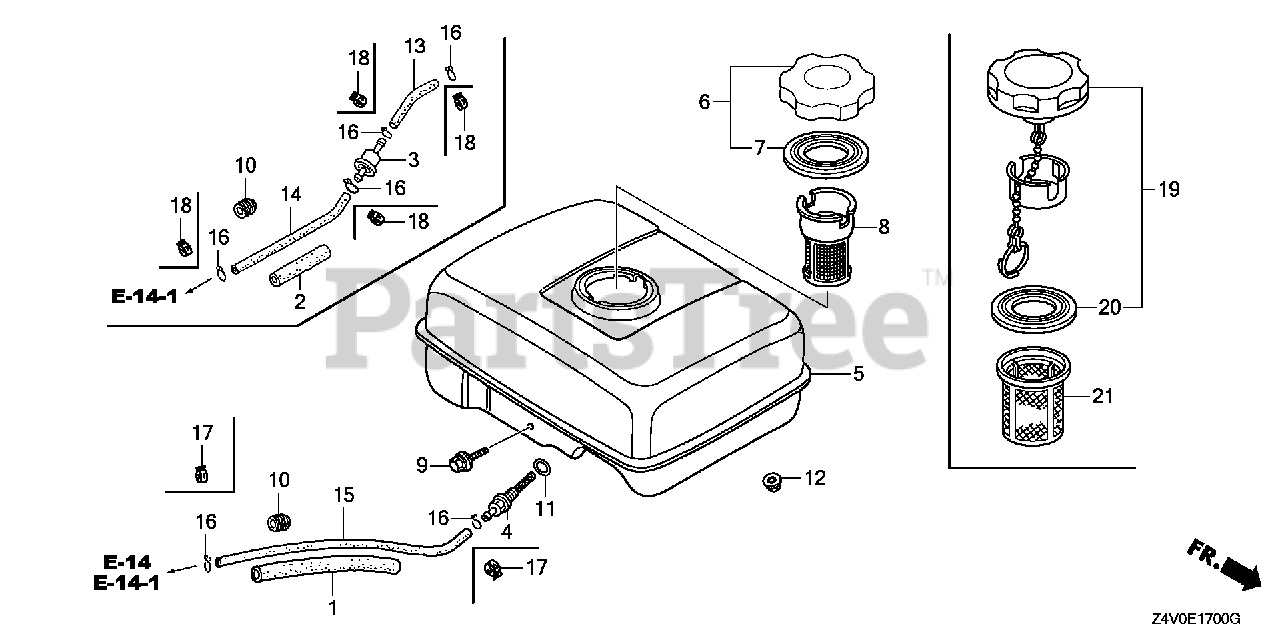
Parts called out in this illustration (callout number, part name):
1	RUBBER, SUPPORTER (107MM)
4	JOINT, FUEL TANK
5	TANK, FUEL *NH31* (MCKINLEY WHITE)
5	TANK, FUEL *NH1* (BLACK)
6	CAP, FUEL FILLER (CHROME PLATED)(RADICON)
7	GASKET, FUEL FILLER CAP (39X62X3) (RADICON)
9	BOLT, FLANGE (6X34)
11	O-RING (13.5X1.5) (ARAI)
11	O-RING (14MM) (NOK)
12	NUT, FLANGE (6MM)
15	TUBE, FUEL (4.5X140) (FKM)
15	BULK HOSE, FUEL (4.5X3000) (4.5X140)
16	CLIP, TUBE (B8)
17	CLAMP, TUBE (D8)
19	CAP, FUEL FILLER
20	GASKET, FUEL FILLER CAP (39X62X3) (RADICON)
20	GASKET, FUEL FILLER CAP (39X62X3)
